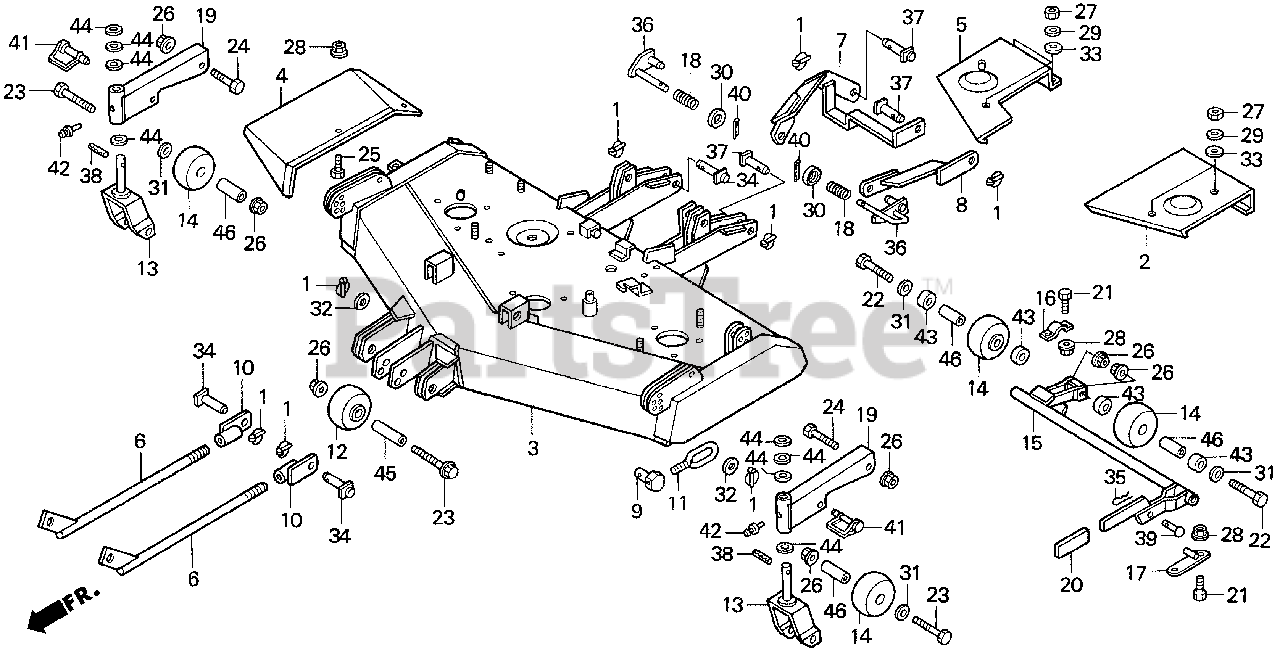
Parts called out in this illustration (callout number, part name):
1	LINCHPIN ASSY.
2	COVER, L. BELT
3	HOUSING, CUTTER (60") (NOT AVAILABLE)
4	ADAPTER, DISCHARGE
5	COVER, R. BELT
6	LINK, FR. DECK
7	LINK, R. RR. DECK
8	LINK, L. RR. DECK
9	PIN, FR. LINK ADJUSTING
10	PLATE, FR. LINK ADJUSTING
11	HOOK, CUTTER DECK
12	ROLLER, ANTI-SCALP (CENTER)
13	ARM, FR. GAUGE ROLLER
14	ROLLER ASSY., GAUGE
15	ARM, GAUGE ROLLER
16	BRACKET, GAUGE ROLLER ARM A
17	BRACKET, GAUGE ROLLER ARM B
18	SPRING, FR. LINK
19	STAY, GAUGE ROLLER
20	GRIP, HEIGHT ADJUST LEVER
21	BOLT (3/8NCX1 HHCS)
22	BOLT (1/2 NCX4-1/2 HHCS GR5)
23	BOLT (1/2NCX5 HHCS)
24	BOLT (1/2NCX2-1/4 HHCS)
25	BOLT (3/8NCX1)
26	NUT (1/2 NC FLANGE LOCK)
27	NUT (3/8NC HEX.)
28	NUT (3/8NC FLANGE HEX. LOCK)
29	WASHER (3/8 STD LOCK)
30	WASHER, SPRING GUIDE
31	WASHER, STD FLAT (1/2)
32	WASHER, STD SAE (5/8)
33	WASHER (3/8 STD FLAT)
34	PIN, LIFT LINK (16)
35	PIN, LOCK (19MM)
36	PIN, RR. LINK
37	PIN, RR. LINK (16)
38	PIN, SPRING (1/4X1-1/2)
39	PIN, GAUGE ROLLER ARM
40	PIN, SPLIT
41	PIN, GAUGE ROLLER
42	NIPPLE, GREASE
43	BEARING, GAUGE ROLLER
44	WASHER (1-1/16X1-9/16X10GA)
45	COLLAR, ANTI-SCALP ROLLER
46	COLLAR (1/2X3/4X3-3/8)
